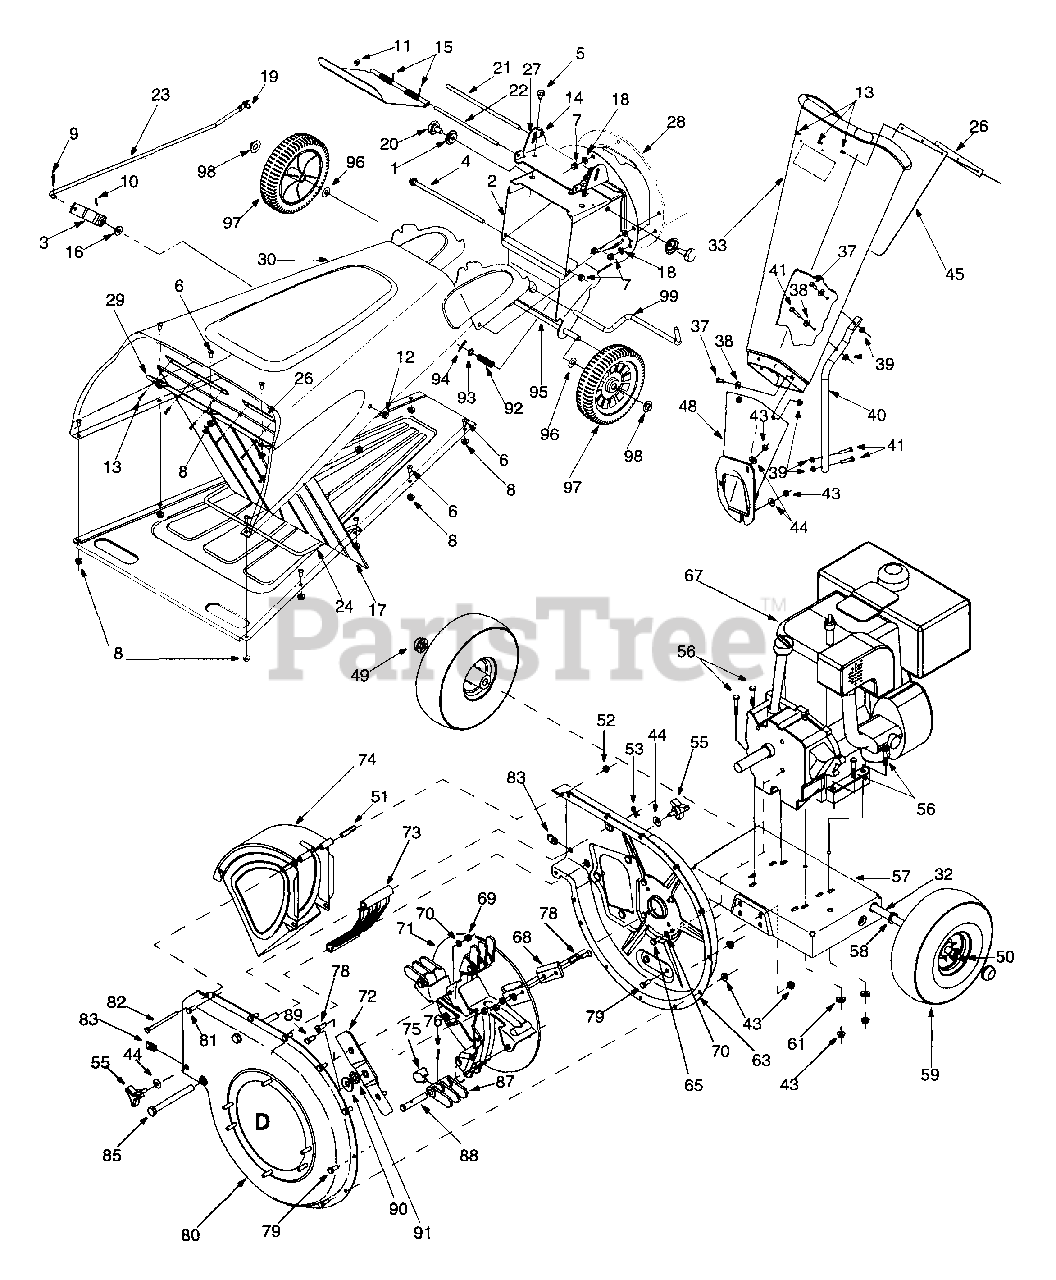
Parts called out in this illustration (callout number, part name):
1	Stop Washer
4	Hex Flange Bolt: 5/16-18 x 8.375" (Gr.5)
5	Hex Washer Head Self-Tapping Screw: 5/16-18 x 0.5"
6	Button-Head Screw 1/4-20 x 0.5"
7	Lock Nut: 5/16-18
8	Hex Flange Lock Nut: 1/4-20
9	Internal Cotter Pin
10	Spiral Pin
11	Cap Nut
12	Speed Cap Nut
13	Pop Rivet
14	Torsion Spring
15	Hopper Door Spring
16	Rubber Washer
17	Hopper Flap
18	Lock Washer
19	Shdr. Scr: .340 x .285 x 1/4-20
20	Shdr. Scr: .56 x .165 x 5/16-18
21	Rel. Rod: 5/16" dia.
22	Hopper Door Rod
23	Flap Retaining Rod
24	Flap Retaining Bail
32	Shredder Axle
33	Chipper Chute
37	Hex Bolt 1/4-20 x .625
38	Flat Washer .28 I.d. x .74 O.d.
39	Flanged Lock Nut
41	Hex Scr. 1/4-20 x .625 (Gr. 2)
43	Hex Nut 5/16-18 Thd. (Gr. 5)
44	Bell Washer .345" I.d. x .88"
45	Shredder Chute Flap
48	Chipper Chute Assembly
49	Push Cap 5/8" dia.
50	Air Valve
51	Chute Hinge Spacer
52	Hex Ctr. Lock Nut 1/4-20 Thd.
53	Internal Cotter Pin
55	Hand Knob
56	Hex Bolt 5/16-18 x 1.5"
58	Flat Washer 1.12 x .64 x .120
59	Wheel Assembly
61	Special Lock Washer
63	Flail Housing Ass'y. - Inner
65	Hex Bolt 5/16-24 x .75" Lg.
67	Engine, Tecumseh
68	Chipper Blade
69	Hex Top Lock Nut 5/16-24 (Gr. 5)
70	Lock Washer 5/16" I.d.
71	Impeller assembly
72	Shredder Blade
73	Shredder Screen
75	Retaining Clip
76	Spring Roll Pin
78	Flat Head Scr 5/16-24 x .75"
79	Hex Bolt 5/16-18 x .75" (Gr. 5)
80	Flail Housing Ass'y. - Outer
82	Hex Bolt 1/4-20 x 3.75"
83	U Nut 5/16-18
85	Clevis Pin
87	Flail Blade
88	Clevis Pin
89	Hex Patch Bolt 3/8-24 x 2.25" (Gr. 8)
90	Lock Washer 3/8"
91	Flat Washer .406" I.d. x 1.25"
92	Compression Spring
93	Flat Washer
94	Internal Cotter Pin
95	Axle Shaft
96	Flat Washer
97	Complete Wheel: Grey
98	Push Cap
99	Lock Rod
